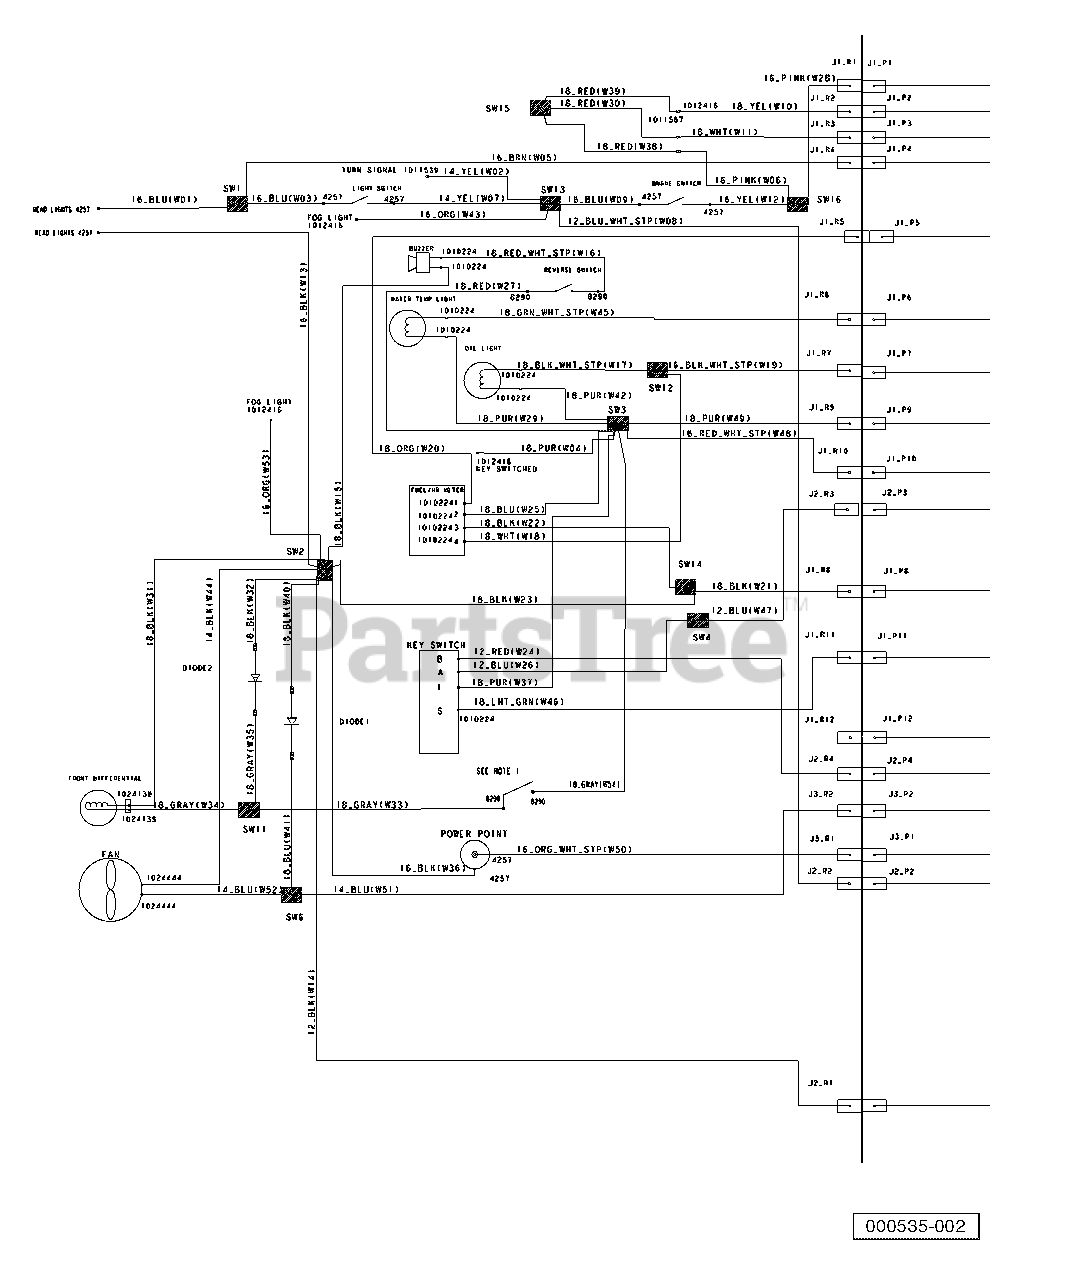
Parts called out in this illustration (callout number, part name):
1	Harness, Restyle Diesel, Front
2	Harness, Restyle Diesel, Rear
3	Asm, Switch, Limit
